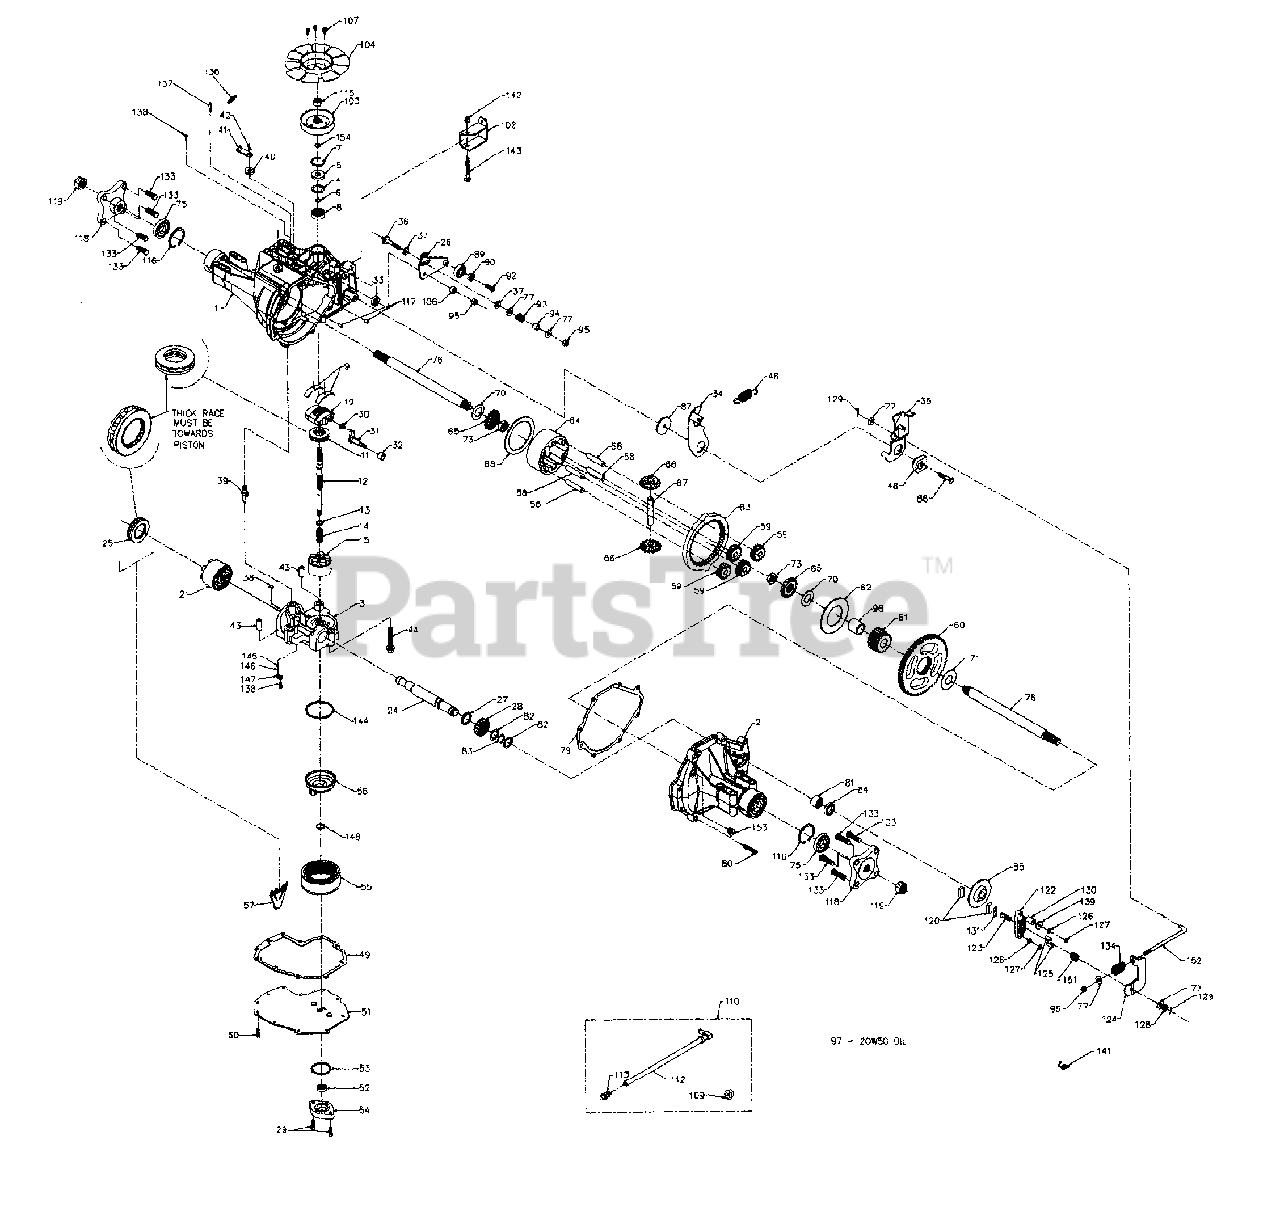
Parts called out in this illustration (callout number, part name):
1	Main Housing Ass'y.
2	R.H. Housing Ass'y.
3	Center Section Ass'y.
6	Wire Retaining Ring
7	Retaining Ring
8	Ball Bearing
9	Cradle Bearing
10	Variable Swashplate
11	Thrust Bearing
13	Block Thrust Washer
15	Cylinder Block Ass'y.
21	Cylinder Block Ass'y.
24	Output Shaft
25	Thrust Bearing
28	16T Pinion Gear
29	Capscrew M6 x 1-20
31	Trunnion Arm
32	Trunnion Bushing
35	Actuating Arm
36	Stud 5/16-24 Thd.
37	Friction Puck
38	Bypass Plate
39	Bypass Actuator
42	Retaining Ring
46	Neutral Spring
48	Adjusting Spring
49	Lower Gasket
50	Self-Tapping Screw
52	Gerotor Ass'y.
54	Gerotor Cover
55	Filter
56	Charge Manifold
57	Retainer, Motor Bearing
58	Pin, Carrier
59	15T Planet Gear
60	67T Spur Gear
61	21T Sun Gear
62	Planet Thrust Plate
63	51T Ring Gear
64	Planetary Carrier
67	Shaft, Differential
68	Differential, Thrust Plate
73	Hex Jam Nut 5/8-18 Thd.
75	Seal
77	Washer
79	Gasket, Main Housing
80	Torx Hd. Scr. 5/15-18 Thd.
81	Needle Bearing
83	Retaining Ring
88	Screw 5/16-24 x 1.75" Lg.
90	Spacer, Locating
92	Countersunk Screw
95	Hex L-Nut 5/16-24 Thd.
96	Sleeve Bearing
97	Oil (.91 Gal.)
102	Torque Bracket
103	Pulley
106	Spacer, Trunnion
109	Vent Bushing
112	Hose Fitting Ass'y.
113	Cap-Vent Ass'y.
116	Retaining Ring
118	Hub
119	Hex Nut 3/4-16 Thd.
120	Puck, Brake
123	Bolt, Square Head
125	Pin, Brake
126	L-Wash. 1/4" I.D.
127	Hex Nut 1/4-20 Thd.
128	Castle Nut
129	Cotter Pin
131	Puck Plate
134	Brake Spring
136	Extension Spring
138	Screw, Self-Tapping 10-32 x .5"
139	Washer .265" I.D. x .875" O.D.
141	Spring, Brake
142	Hex L-Nut 5/16-18 Thd.
143	Bolt 5/16-18 x 2.5" Lg.
145	Relief Spring
147	Plate, Relief
151	Brake Comp. Spring
152	Brake Pull Rod
154	Wire Retaining Ring
